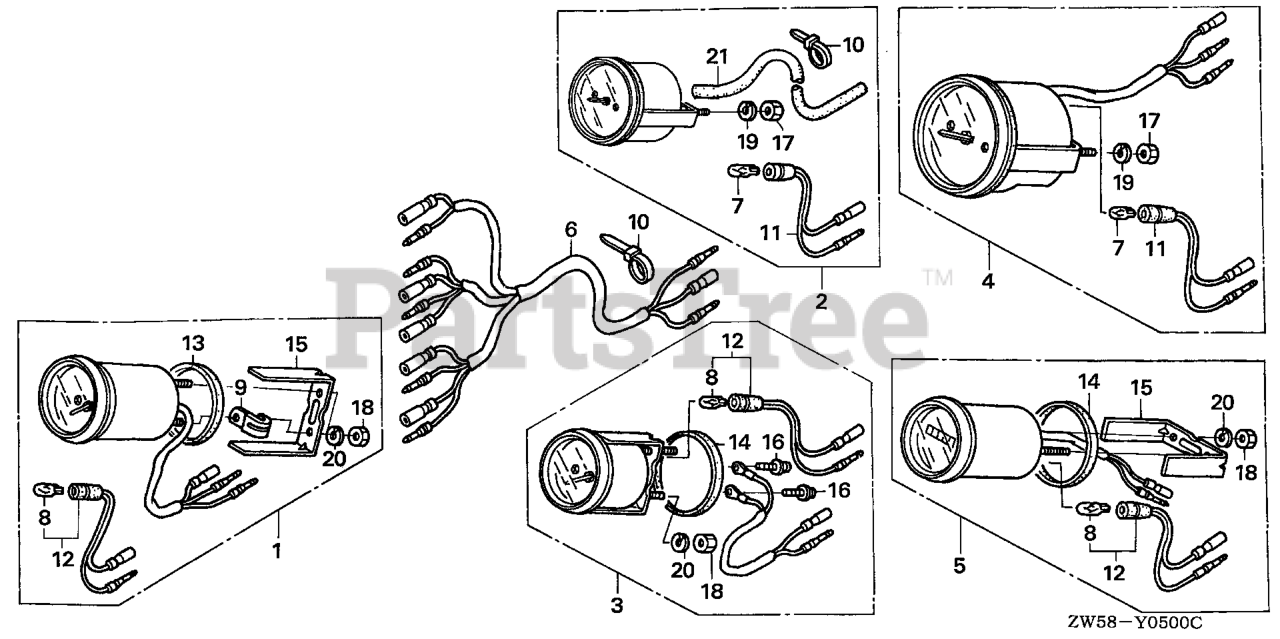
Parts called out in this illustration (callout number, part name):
1	METER KIT, TRIM (WHITE)
1	METER KIT, TRIM (B) (BLACK)
2	SPEEDOMETER KIT (WHITE)
2	SPEEDOMETER KIT *NHA85* (B) (BLACK)
3	METER KIT, VOLT (WHITE)
3	METER KIT, VOLT *NHA85* (B) (BLACK)
4	METER KIT, TACHO
4	METER KIT, TACHO (B)
5	METER KIT, HOUR (WHITE) (NA USE ALT:39700-ZW5-000ZA)
5	METER KIT, HOUR (B) (NA USE ALT:39700-ZW5-000ZA)
6	HARNESS ASSY., METER (B)
7	BULB, WEDGE BASE (T10) (12V 1.7W) (STANLEY)
8	BULB, WEDGE BASE (12V1.7W) (TOSHIBA)
9	CLAMP
10	BAND, SELF-LOCK
11	SOCKET
12	SOCKET
13	GASKET (TO 1015209) (FROM 1015210)
14	GASKET
15	BRACKET (TO 1015209) (FROM 1015210)
16	SCREW-WASHER (3X22)
17	NUT, HEX. (5MM)
18	NUT, HEX. (4MM)
19	WASHER, SPRING (5MM)
20	WASHER, SPRING (4MM)
21	TUBE, SPEED METER (4X7X8000)
